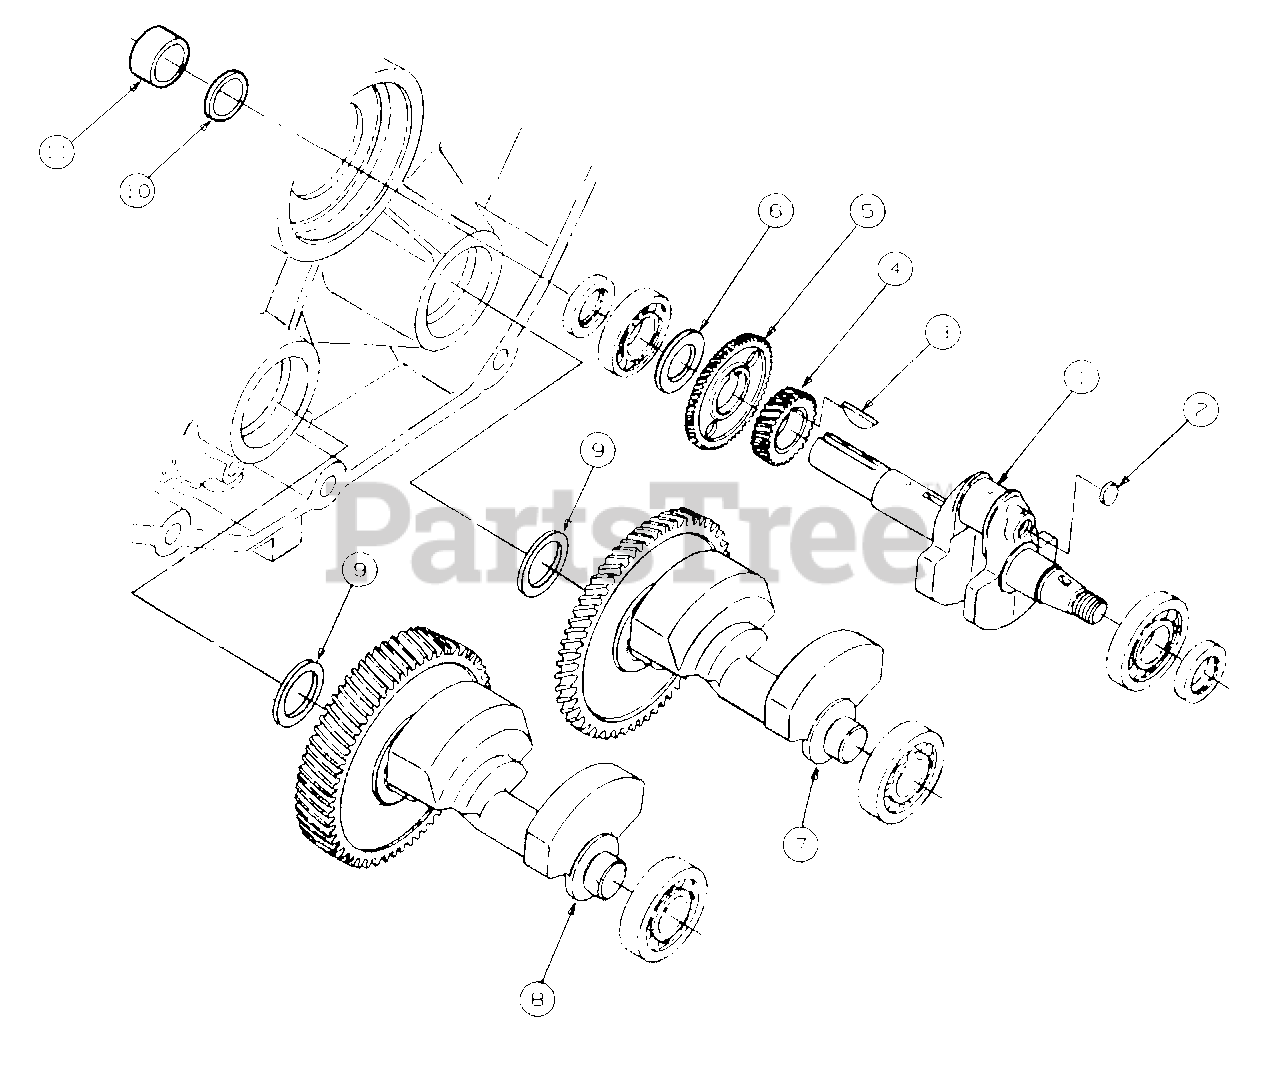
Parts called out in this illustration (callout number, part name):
1	Crankshaft Assy
2	Plug, Expansion
3	Key, Crankshaft Gear
4	Gear, Crankshaft
5	Gear, Balancer
6	Shim, Crankshaft 0.2 mm
7	Shaft Assy, Balancer
8	Shaft Assy, Balancer
9	Shim, Shaft, Balancer 0.5 mm
10	Washer, Spacer
